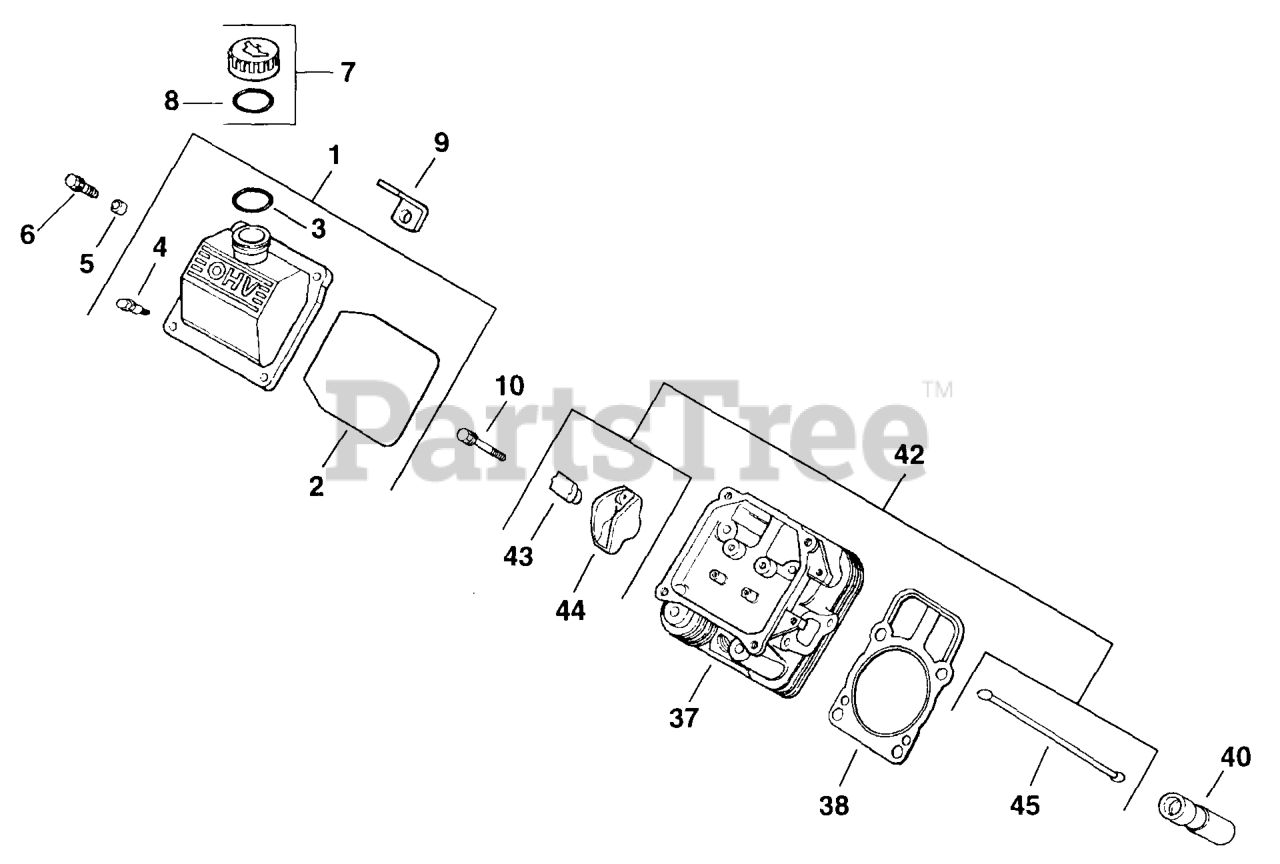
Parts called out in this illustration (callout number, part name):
1	VALVE COVER KIT-USE 24 755 140-S
2	O-RING - USE 24 153 16
3	O-RING-USE 24 153 32-S
4	SCREW, SHOULDER
7	KIT, OIL FILL CAP (BLACK)
8	O-RING - USE 25 153 02-S
9	STRAP, LIFTING-USE 25 445 03-S
10	Screw, hex. flange M6x1.0x34
38	GASKET - USE 24 041 32
40	LIFTER - USE 12 351 02
42	KIT, VALVE TRAIN
43	PIVOT, CYLINDRICAL ROCKER ARM-USE 24 599 02-S
44	ARM, ROCKER
45	ROD, PUSH
